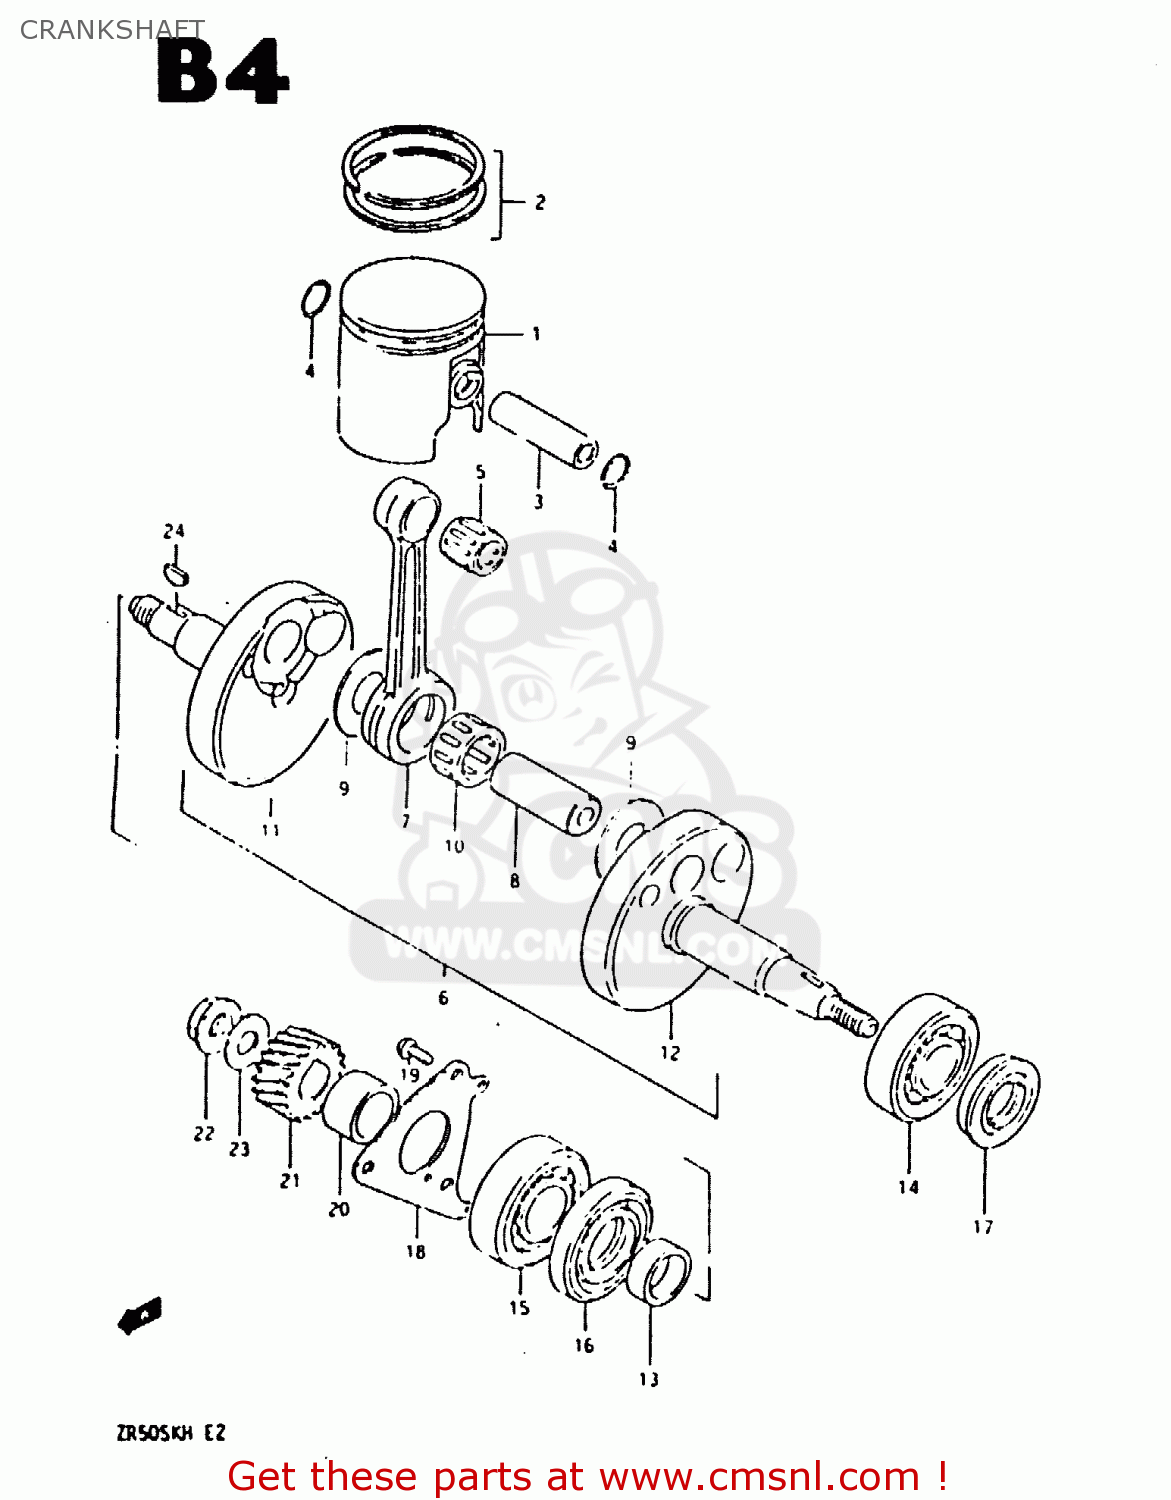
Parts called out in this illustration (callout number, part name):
1	PISTON
2	RING SET,PISTON
3	PIN,PISTON
4	RING,SNAP
5	ROLLER BEARING (12X16X1
6	CRANKSHAFT ASSEMBLY
7	CONNECTING ROD
8	PIN,CRANK
9	WASHER(16X29X1)
10	BEARING
11	CRANKSHAFT
12	CRANKSHAFT,LEFT
13	SPACER(20X26X9)
14	BEARING
15	BEARING(20X47X14)
16	SEAL,OIL(26X47X7.3)
17	SEAL,OIL(19.6X37X8)
18	RETAINER,CRANKSHAFT BEARING,R
19	SCREW 6X12
20	SPACER(20X26X14)
21	GEAR,PRIMARY DRIVE NO.19
22	NUT
23	WASHER
24	KEY
